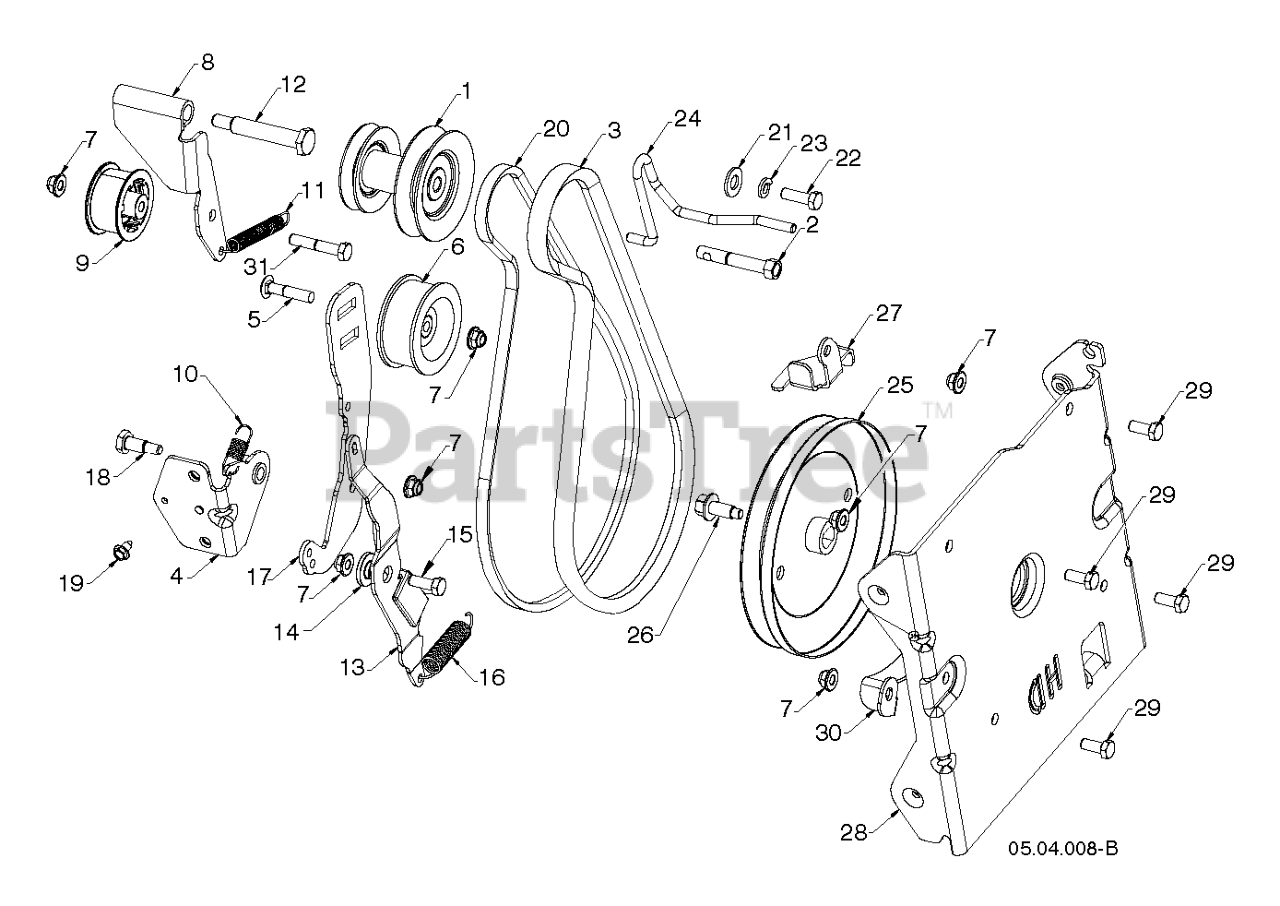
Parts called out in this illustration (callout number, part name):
1	PULLEY WELDMENT
2	BOLT.ENGINE.PULLEY
3	BELT 5L 39.15L
4	BRACKET WELDMENT, IDLER ARM ZI
5	BOLT 5/16-18 CARRIAGE 1.5L
7	NUT HEXAGON FLANGE 5/16-18 ST
8	ARM DRIVE IDLER CLEAR ZINC PLA
9	PULLEYIDLER.2.0.W/SPACER.CZ
10	SPRING IDLER RETURN
11	SPRING RETURN IDLER ARM
12	BOLT 5/16-24X2.25 HEX HEAD SHO
13	ARM IMPELLER BRAKE
14	BUSHING.BRAKE.ARM
15	BOLT HEXAGON BOLT 5/16-18 X 7/
16	SPRING EXTENSION - BRAKE
17	ARM IDLER BLACK ZINC
18	SCREW HEX HEAD SHOULDER
20	BELT 3L 39.68; POLY CORD
21	WASHER 11/32 X 11/16 X 14 GA T
22	SCREW 5/16-24 X .75 GR5
23	WASHER SPRING LOCK WASHER WITH
24	GUIDE.BELT.5L.IMPELLER.3L.DRV
25	PULLEY IMPELLER DD 5L HD
26	SCREW HEXAGON HEAD FLANGE 3/8-
28	BRACKET AUGER HOUSING INTERFAC
29	SCREW HEXAGON HEAD SCREW 5/16-
30	BRACKET.BELT.KEEPER.LOWER.BLAC
31	BOLT, HEX 5/16-18X1-3/4
